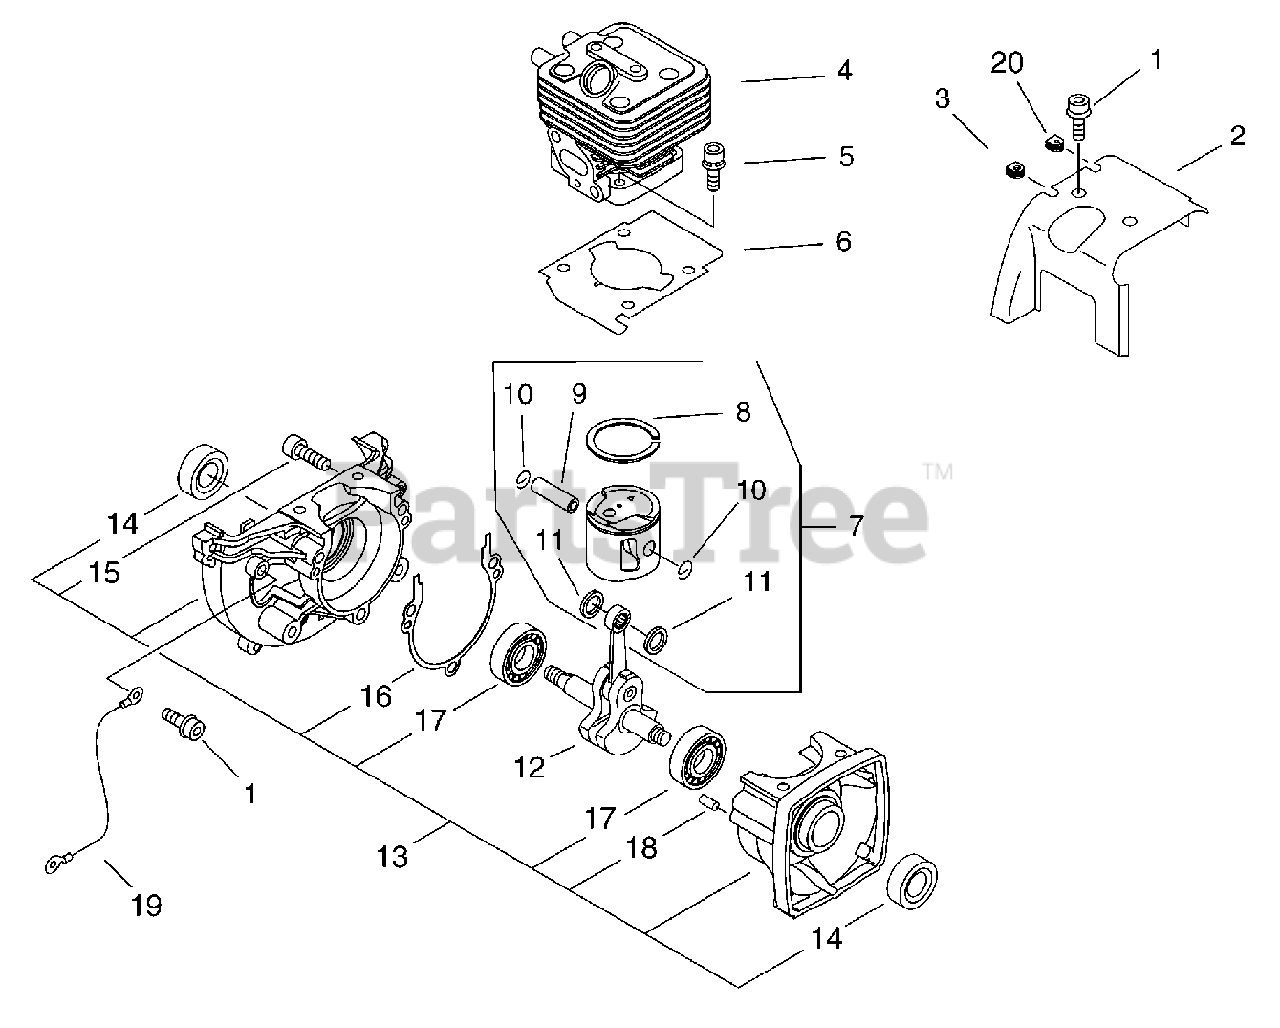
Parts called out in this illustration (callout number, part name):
1	BOLT 5×8
2	COVER, CYLINDER
4	CYLINDER
5	BOLT 5×25
6	GASKET, CYLINDER
7	PISTON KIT
8	RING, PISTON
9	PIN, PISTON
10	RING, SNAP
11	WASHER, THRUST
12	CRANKSHAFT ASSY
13	CRANKCASE KIT
14	SEAL, OIL 12
15	BOLT 5×28
16	GASKET, CRANKCASE
17	BEARING, BALL - 6201 C3
18	PIN, LOCATING 4×8
19	LEAD - GROUND
